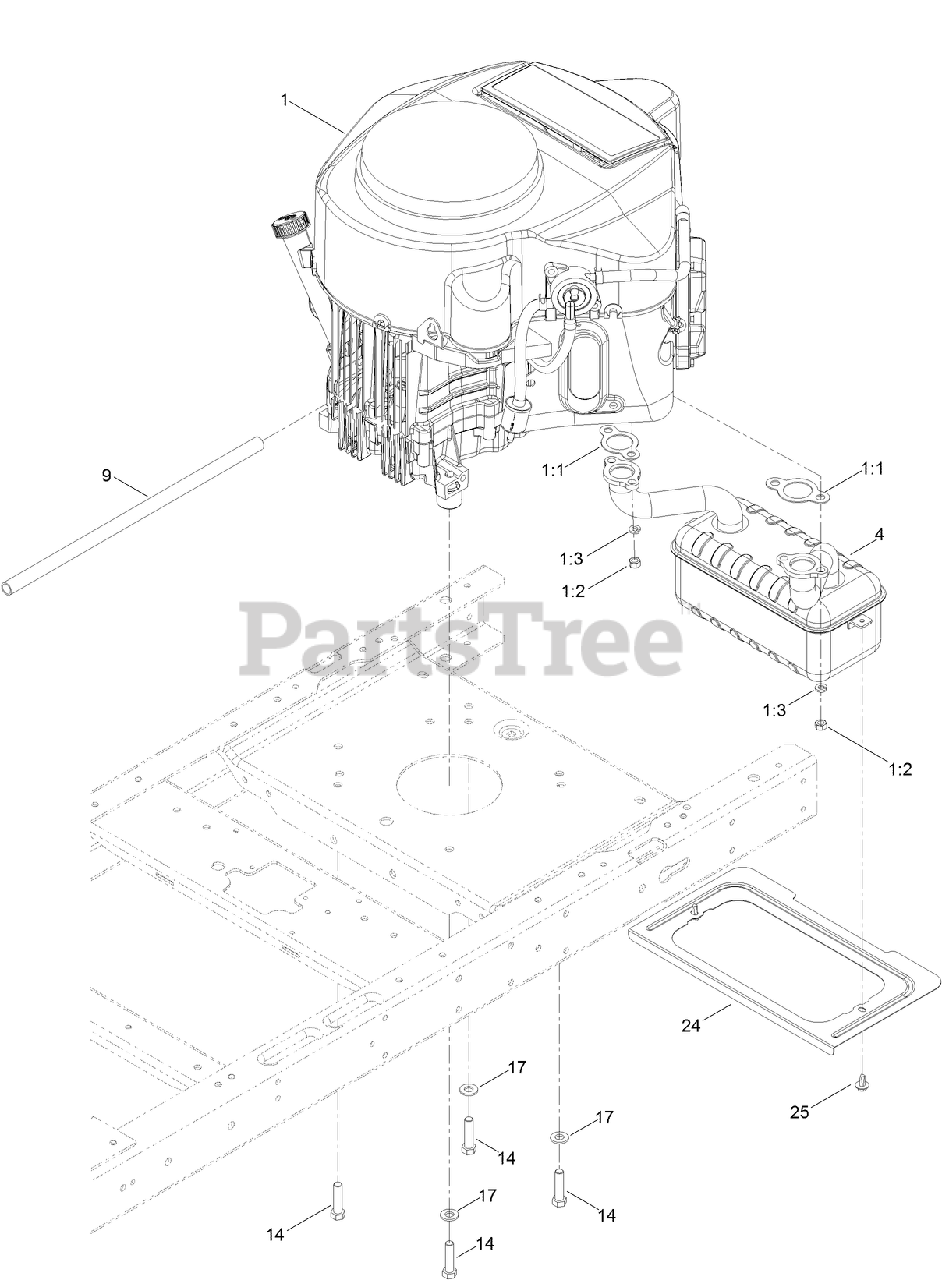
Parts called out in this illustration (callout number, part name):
1:1	GASKET-EXHAUST
1:3	WASHER-LOCK
4	MUFFLER
9	TUBE-DRAIN, OIL
14	BOLT-HH
17	WASHER-FLAT
24	SHIELD-HEAT
25	SCREW-HHFTF
